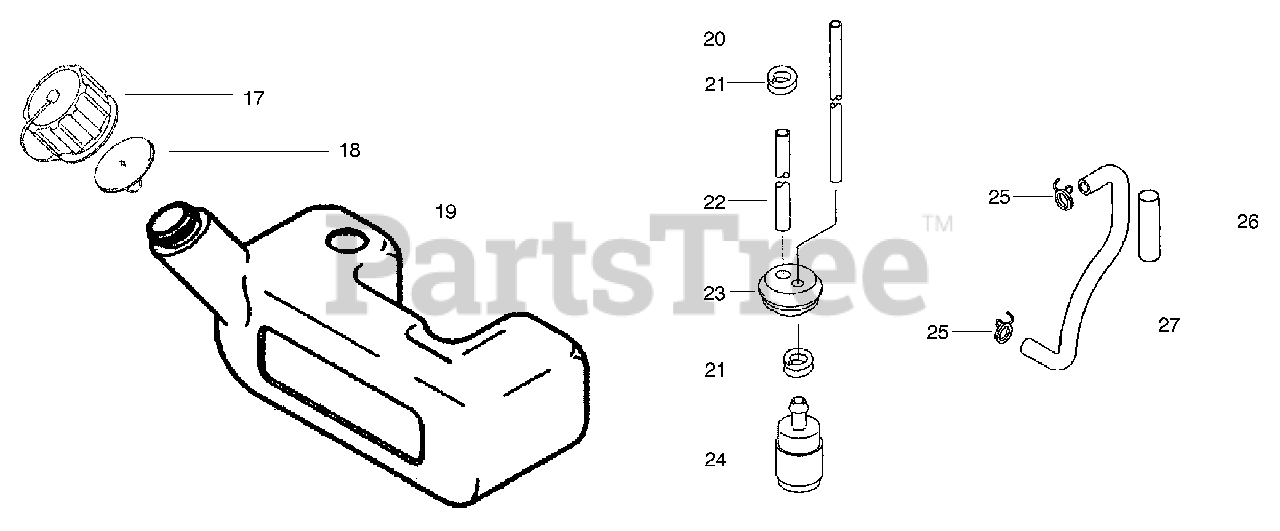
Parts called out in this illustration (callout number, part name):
17	Assy-Tank Cap
18	Assy-Valve
19	Tank-Fuel
20	Tube 3x5x250
21	Clamp-Fuel Filter
22	Tube 3x6x130
23	Grommet-Tank
24	Filter-Fuel
26	Tube-10x11x35
